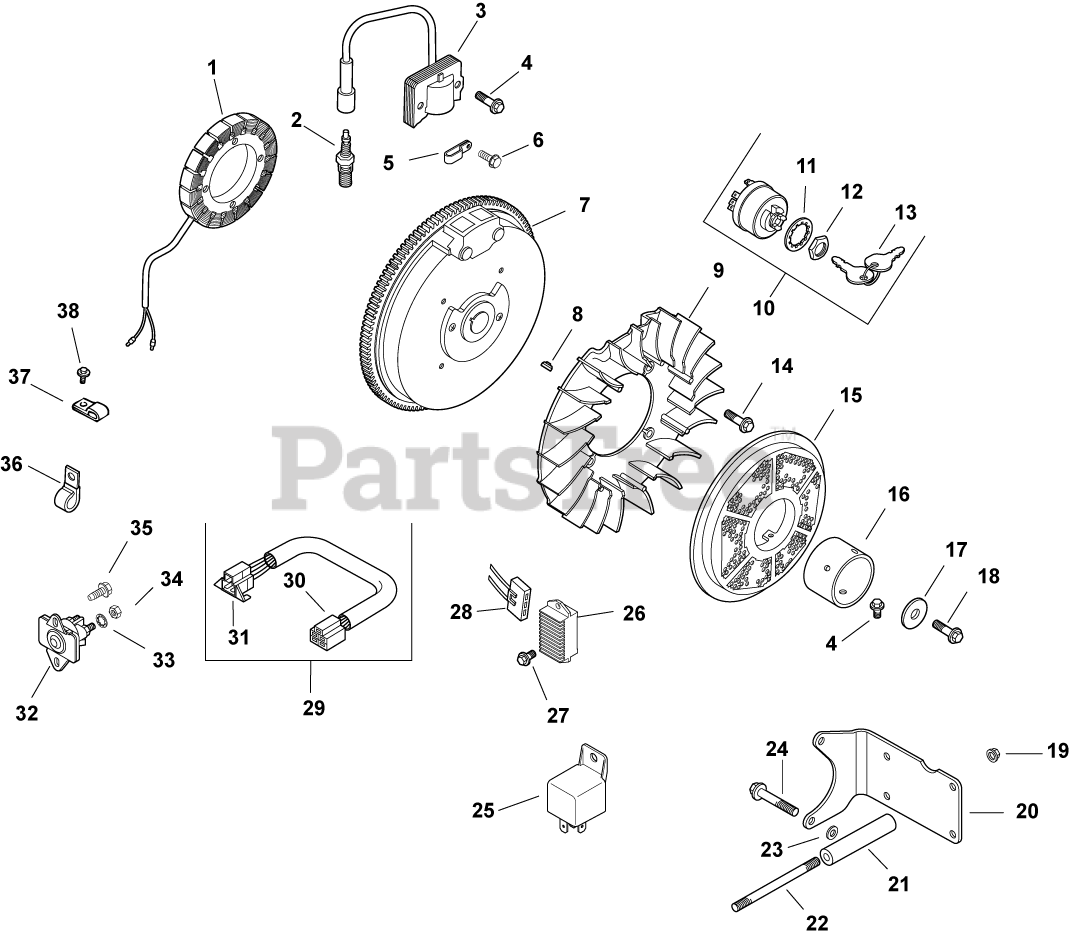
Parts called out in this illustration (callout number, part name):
1	KIT, 25 AMP STATOR ASSY.
2	PLUG, SPARK (PRO SERIES)
3	MODULE, IGNITION
4	SCREW, FLG THD FRM M5X.8X20-(#25086399S)
6	SCREW, FLG THD FRM M5X.8X10
7	FLYWHEEL - USE 12 025 72-S
8	KEY, 3/16" X 5/8"
9	FAN - DISCONTINUED
10	SWITCH ASSY, KEY (KM)-USE 25 099 32-S
11	WASHER, INTERNAL TOOTH
12	NUT, KEY SWITCH
13	KEY, SET -USE 48 340 01-S
14	BOLT, SHOULDER
15	SCREEN, GRASS (BLACK)
16	CUP, DRIVE STARTER - DISCONTINUED
17	WASHER, FLAT 13/32"
18	SCREW, FLG M10X1.5X45 - (#25086361S)
19	NUT, FLG M8X1.25
20	BRACKET, FUEL TANK
22	STUD, M8X1.25X133-USE 25 755 54-S
23	WASHER, FLAT 11/32"
24	SCREW, HEX FLANGE -USE 24 086 17-S
26	REG/RECTIFIER (20/25 AMP)-USE 25 403 20-
27	SCREW, FLG M6X1.0X16
28	CONNECTOR, BODY (KM)-USE 25 155 41-S
29	CONNECTOR ASSEMBLY
30	CONNECTOR
31	CONNECTOR
32	SOLENOID - WATERPROOF (KM)-USE 25 435 08
33	WASHER, INT TOOTH LOCK 1/4"
34	NUT, JAM 1/4-20 GRADE 2
35	SCREW,FLG THD FRM M6X1.0X16-(#25086397S)
36	CLIP, CABLE
38	SCREW, THD FROM M5X0.8X30
